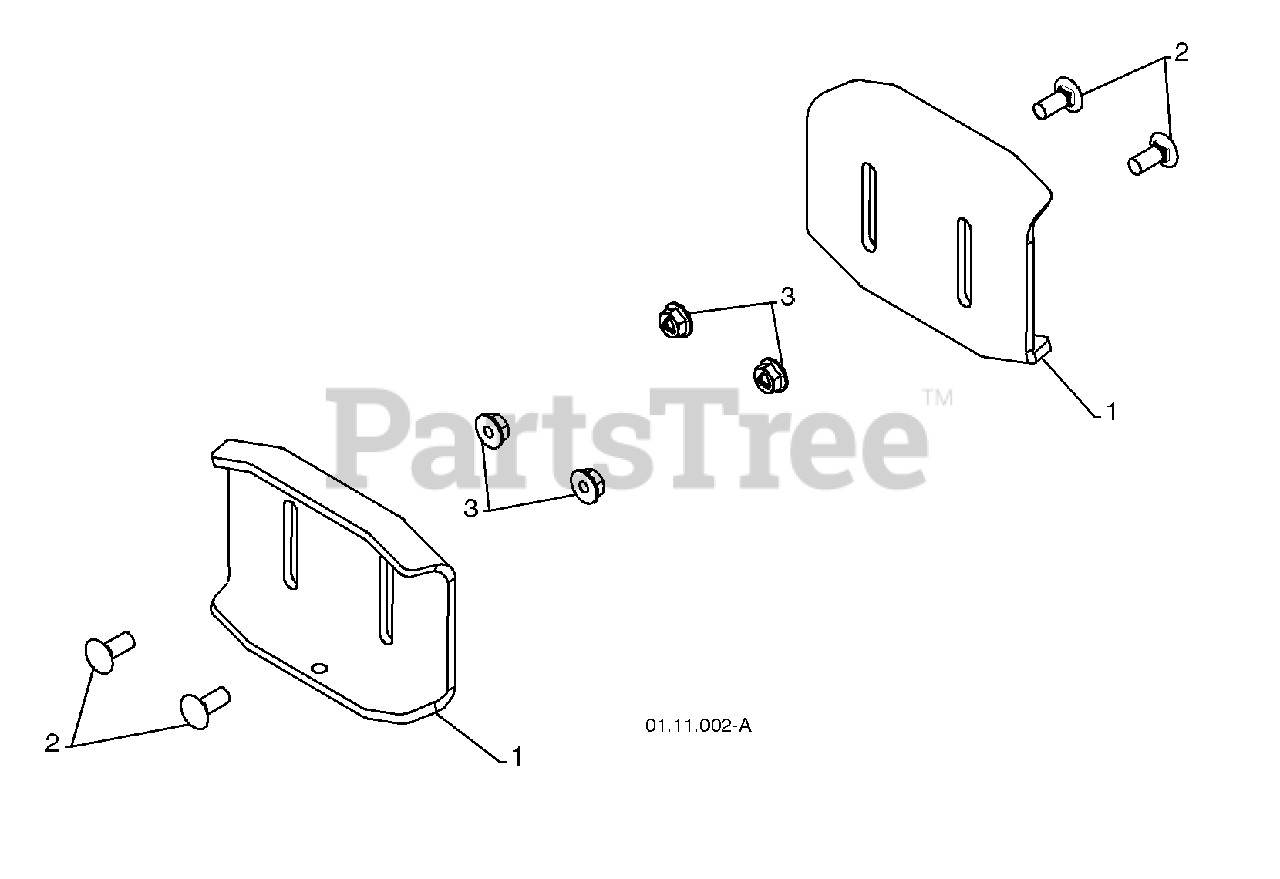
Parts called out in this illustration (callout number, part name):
1	SKID PLATE
2	CARRIAGE BOLT 5/16-18 X .750
3	NUT 5/16-18
